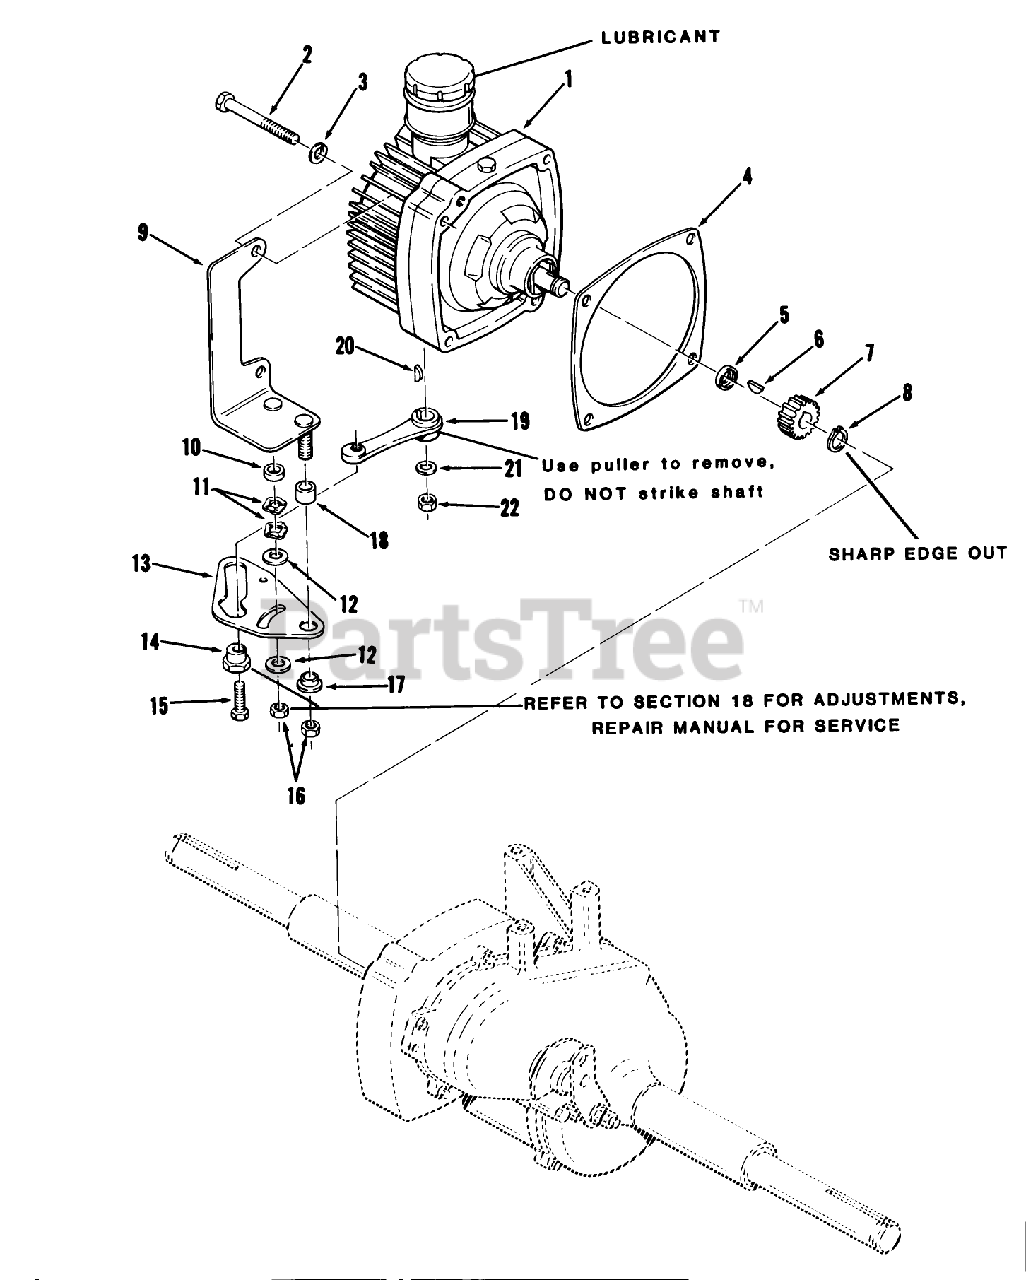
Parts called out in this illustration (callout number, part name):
6	KEY WOODR 1/8X1/2 DI
10	SPACER-FRICTION
11	WASHER-SPRING DISC
12	FRICTION WASHER
13	CAM-SPEED CONTROL (NS)
16	NUT-HEX
17	CAM-SPACER
18	SPACER-PIVOT
19	ARM-SPEED CONTROL
20	KEY WOODR 1/8X1/2 DI
